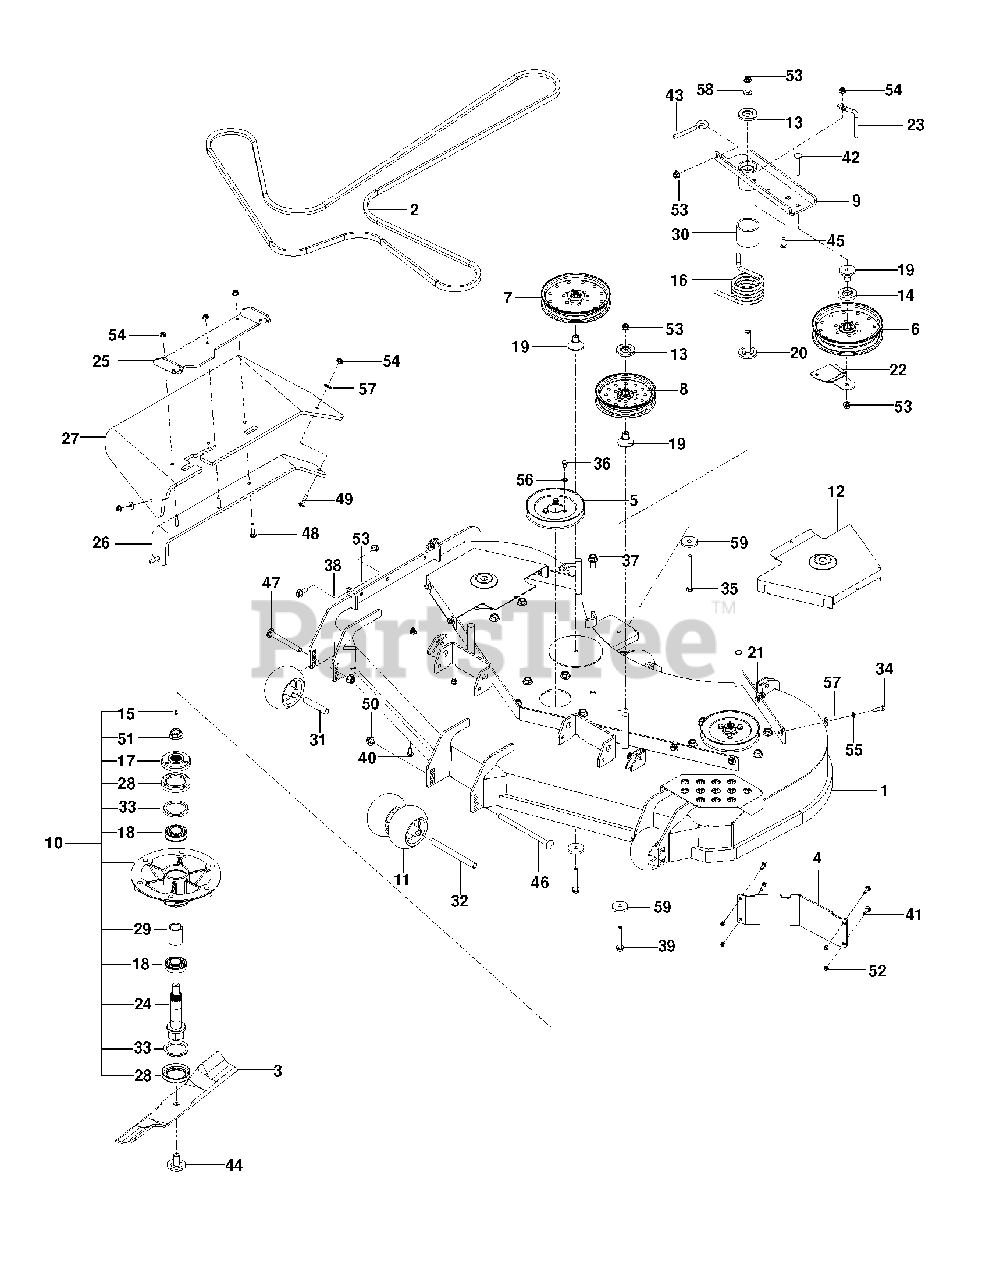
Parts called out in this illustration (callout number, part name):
1	DECK W/SAFETY DECALS 60"
2	BELT, "5V", 176"
4	BAFFLE, DIVERTER 54"/60" LH
6	PULLEY - IDLER 7"
7	PULLEY - 7" NARROW
8	PULLEY IDLER, 6" NARROW
10	SPINDLE ASM. 10"
11	ROLLER, GAUGE .635 BORN
13	DUST SHIELD
14	SHIELD, DUST
15	ZERK
17	HUB - PULLEY
18	BEARING - 206KRR8
19	BEARING, IDLER ARM
20	BEARING, IDLER PIVOT
21	U-CLIP 5/16-18 NUT RETAINER
22	BELT GUIDE, BLK
24	SHAFT - SPINDLE
25	BRKT - CHUTE MTG BLACK
26	BRKT, CHUTE SUPPORT BLACK
27	CHUTE, DISCHARGE 48-52
28	CUP - DEBRIS
29	SPACER - BEARING
31	TUBE, ROLLER AXLE
32	TUBE, ROLLER AXLE LONG
33	V-RING, 55MM
34	HCS 5/16C X 1
35	HCS 3/8-16 X 4-1/2 GR 8 ZD
36	HCS 5/16-18 X 1/2 GR 5 ZD
38	HHFS 3/8-16 X 1 GRD 5 ZD
39	HHFS 3/8-16 X 2 3/4
40	BOLT, CARRIAGE 5/16X1-1/4
42	CARRIAGE BOLT 3/8-16 X
44	BLADE BOLT/WASHER
45	RHSSNB 5/16C X 1.0
46	RHSNB 1/2-13 X 8 GR5 ZD
47	RHSNB 1/2-13 X 4.75 GR5 ZD
48	RHSNB 5/16-18 X 1-1/2 GR 5 ZD
49	BOLT, CARRIAGE 5/16X1-1/4
50	NUT, 1/2-13 HEX FLG NYLOC ZD
51	NUT FLANGE 3/4-16
52	NUT 1/4-20 NYLOC
53	NUT 3/8-16 HEX FLG NYLOC ZD
54	5/16-18 NYLOC FLANGE NUT
55	WASHER 5/16 LOCK
56	WASH 5/16 DISC SPRING ZD
57	WASHER 5/16 FLAT
58	WASHER, 3/8 THICK
59	SPINDLE WASHER
